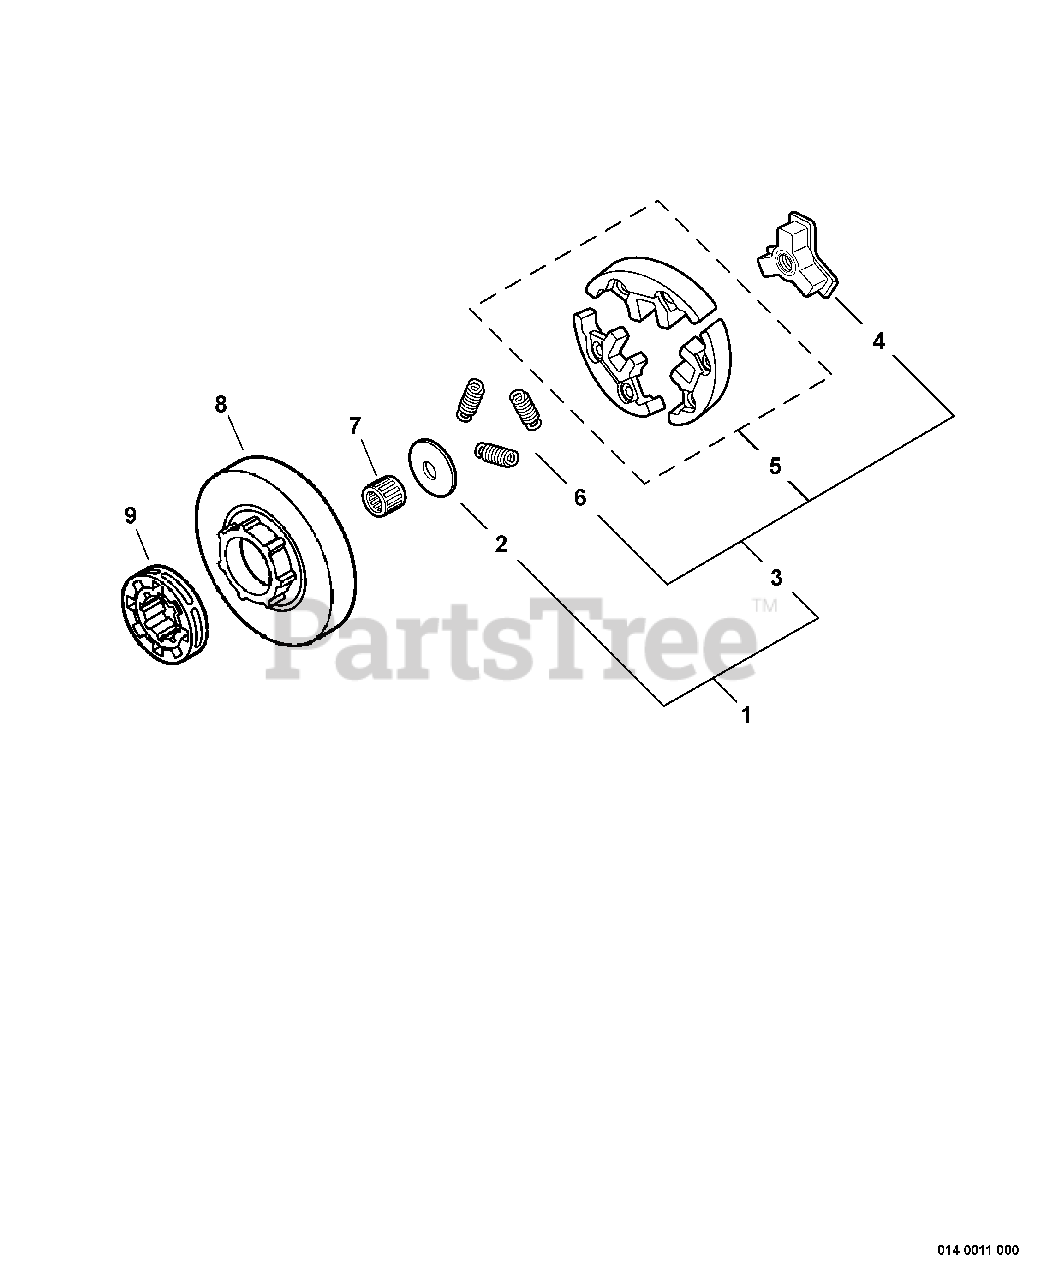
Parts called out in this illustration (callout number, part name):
1	CLUTCH ASSY
2	PLATE, CLUTCH
3	CLUTCH ASSY
4	HUB, CLUTCH
5	SHOE SET, CLUTCH (3PCS)
6	SPRING, TENSION
7	BEARING, NEEDLE
8	DRUM, CLUTCH
9	SPROCKET, RIM 3/8"×7T
